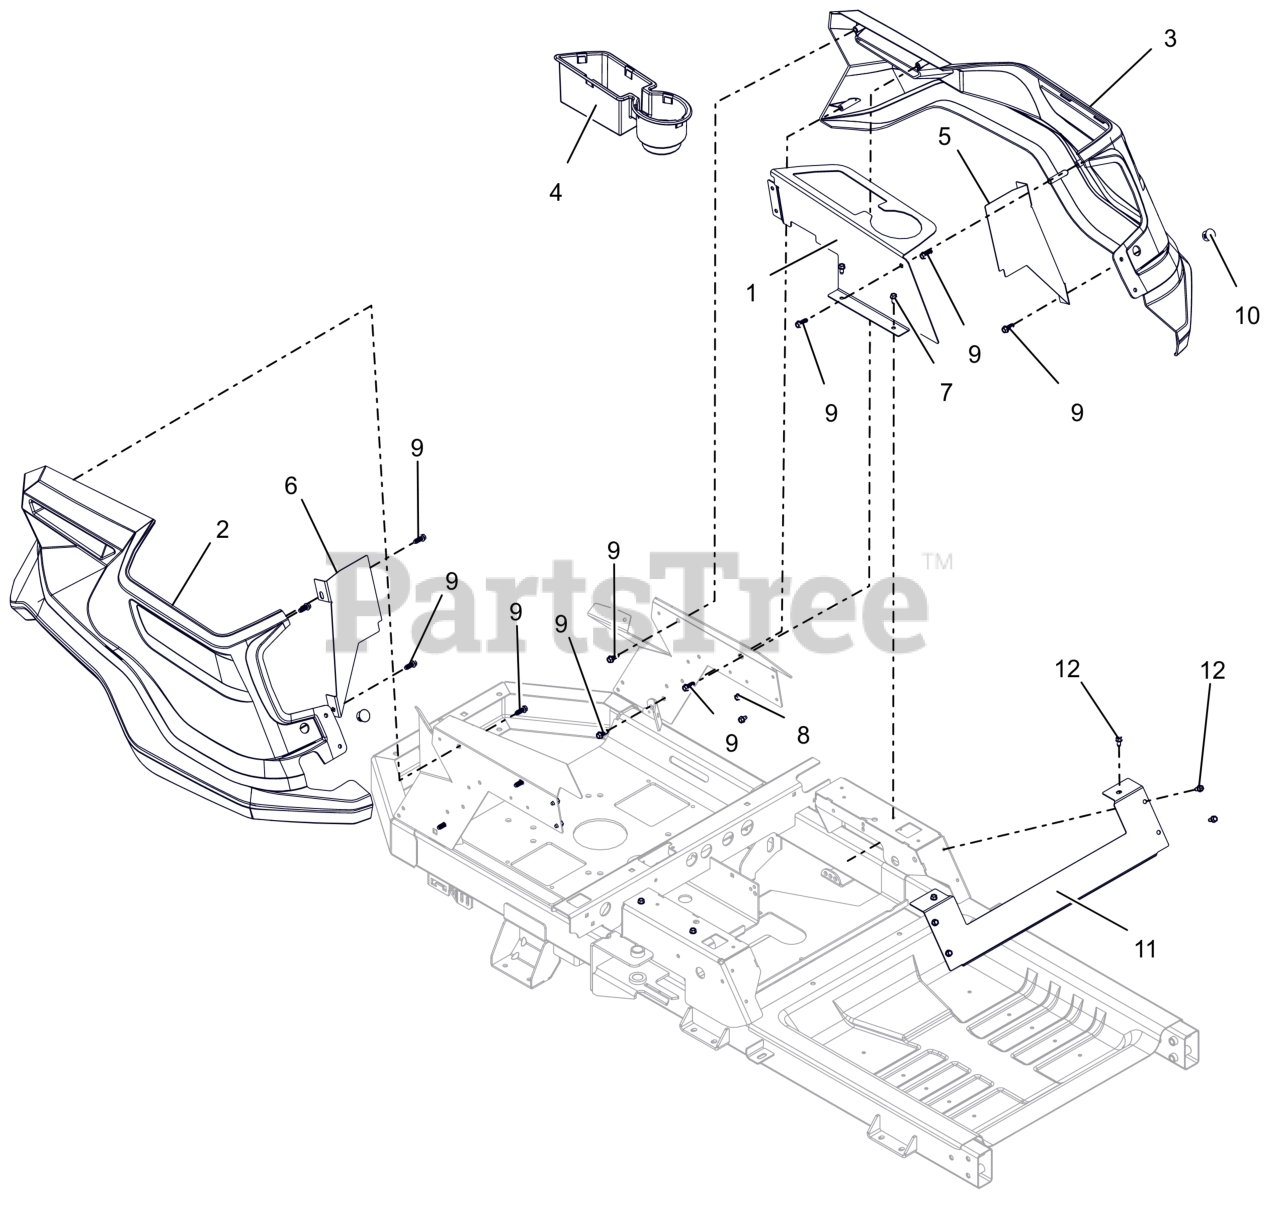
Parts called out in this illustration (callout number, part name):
1	PANEL, LEFT SIDE FENDER MOUNT
2	FENDER, RH IKON
3	FENDER, LH IKON
4	INSERT, CUP/STORAGE HOLDER
5	PLATE, LH BLOCKER
6	PLATE, RH BLOCKER
7	SCR-TAP .25-20X.50 HWH ZCC
8	SCR,TAP .25-20X.375 HWH TR ZCC
9	SCR-.312X.75 #14H H/W/H H/L CZ
10	PLUG, HOLE .75 (BLACK)
11	PLATE, SEAT KICK
12	SCR-TAP .25-20X.50 HWH ZCC
